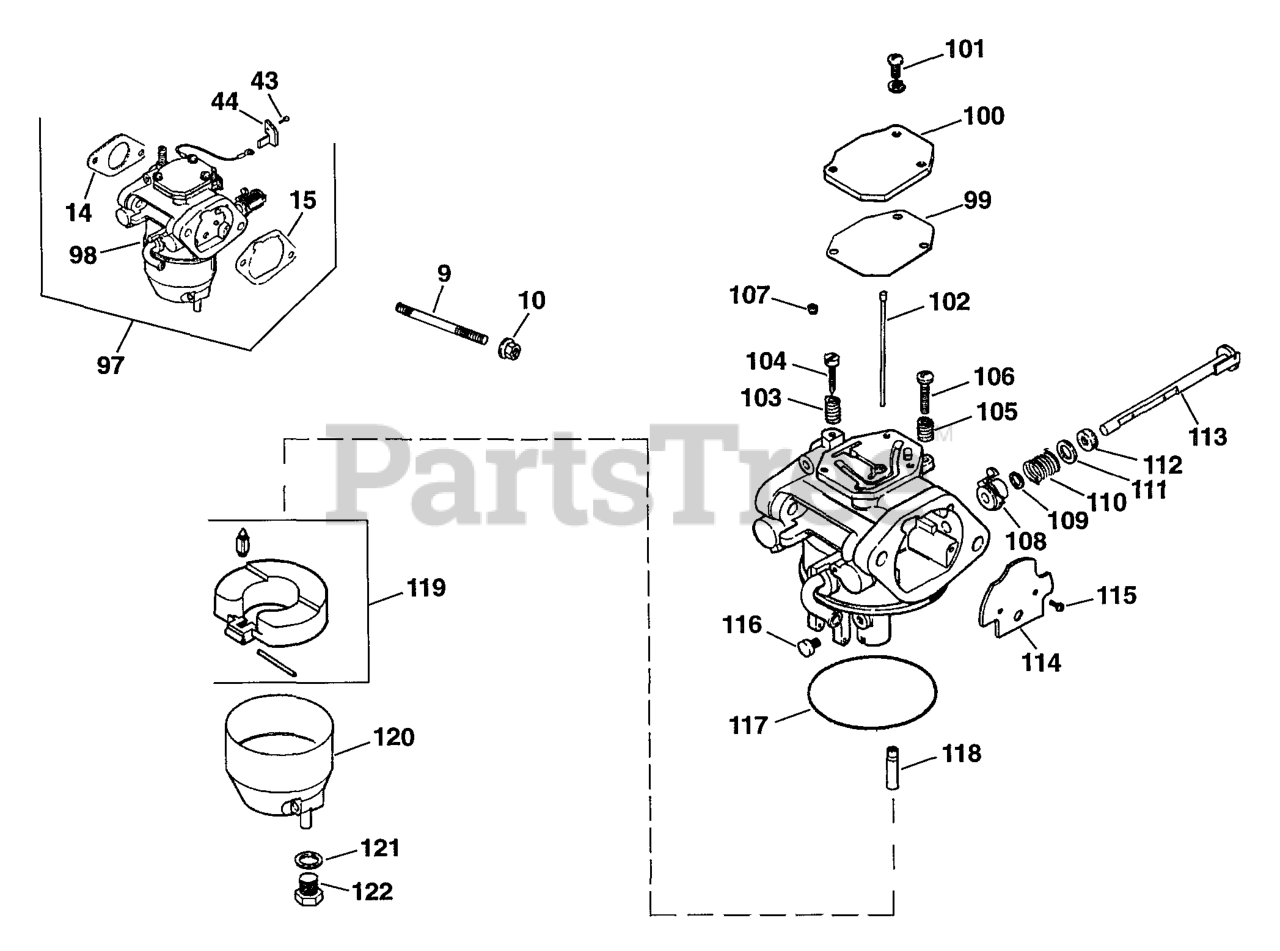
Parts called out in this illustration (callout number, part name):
9	Stud, M6x1.0x128
10	Nut, Hex. M6x1.0
14	Gasket, Carburetor
15	Gasket, Air Cleaner Base
43	Bracket, Throttle Stop
44	Screw, Phillips Hd. M2x0.45x6
